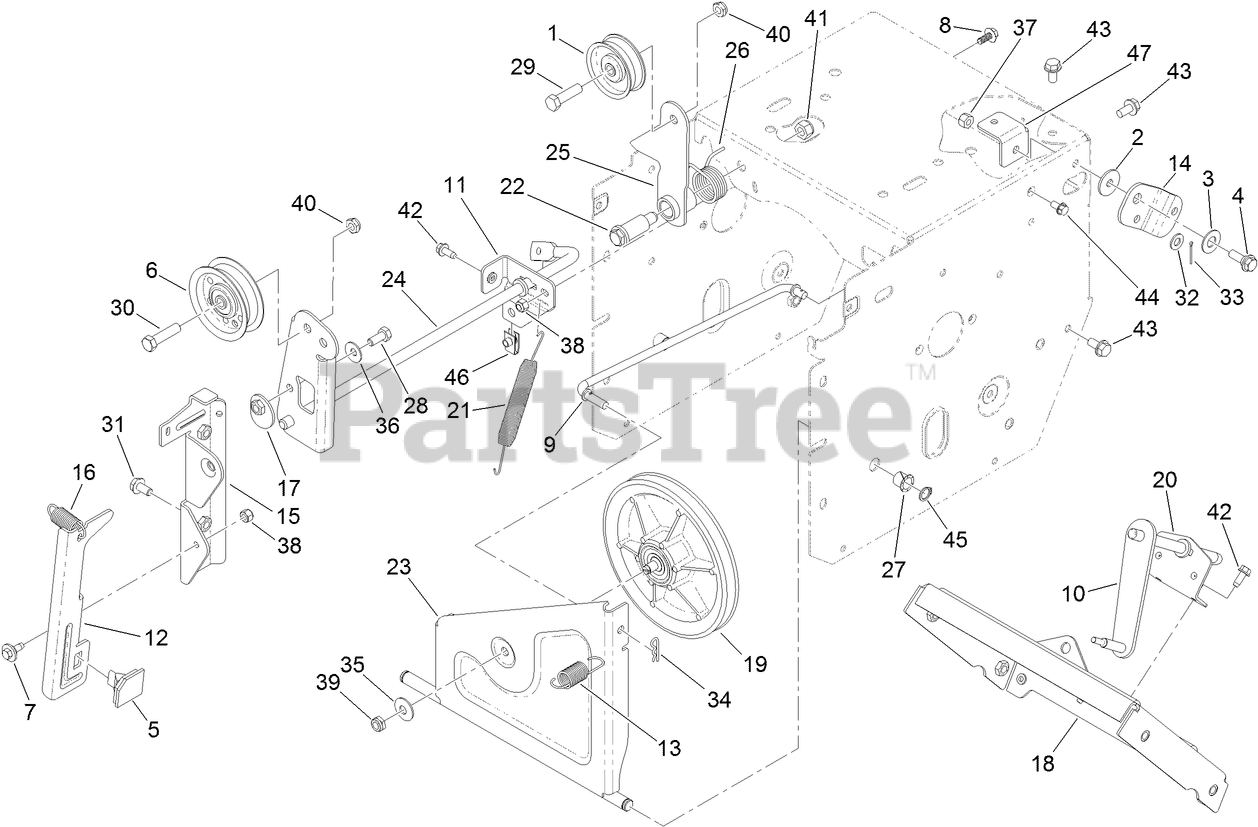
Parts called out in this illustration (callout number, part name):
1	PULLEY-IDLER
2	WASHER-PIVOT
3	WASHER
4	SCREW-SHOULDER
5	PAD-BRAKE
6	PULLEY-IDLER
7	SCREW-SHOULDER
8	SCREW-HHF
9	LINK-CONTROL, SPEED
10	LEVER-CONTROL, TRACTION
11	BRACKET-CLUTCH, IMPELLER
13	SPRING-EXTENSION
14	BELLCRANK-DRIVE
16	SPRING-EXTENSION
18	SHIFT PLATE ASM
19	PULLEY-TRACTION
20	BRACKET-ROD, SHIFT
22	BOLT-SHOULDER
23	BRACKET-WHEEL, FRICTION
24	IMPELLER CLUTCH ASM
25	ARM-IDLER, TRACTION
26	SPRING-TORSION
27	BUSHING-NYLINER
28	SCREW-HH
29	SCREW-HH
30	SCREW-HH
31	SCREW-HH
32	WASHER-PLAIN
33	SCREW-HH
35	WASHER-BELLEVILLE
36	WASHER-BELLEVILLE
37	NUT-LOCK, NI
38	NUT-LOCK, NI
39	NUT-HEX
41	NUT-LOCK, NI
42	SCREW-HWH
43	SCREW-HWHTF
44	SCREW-HWH
45	RING-RETAINING
47	BRACKET-FRAME, LH
